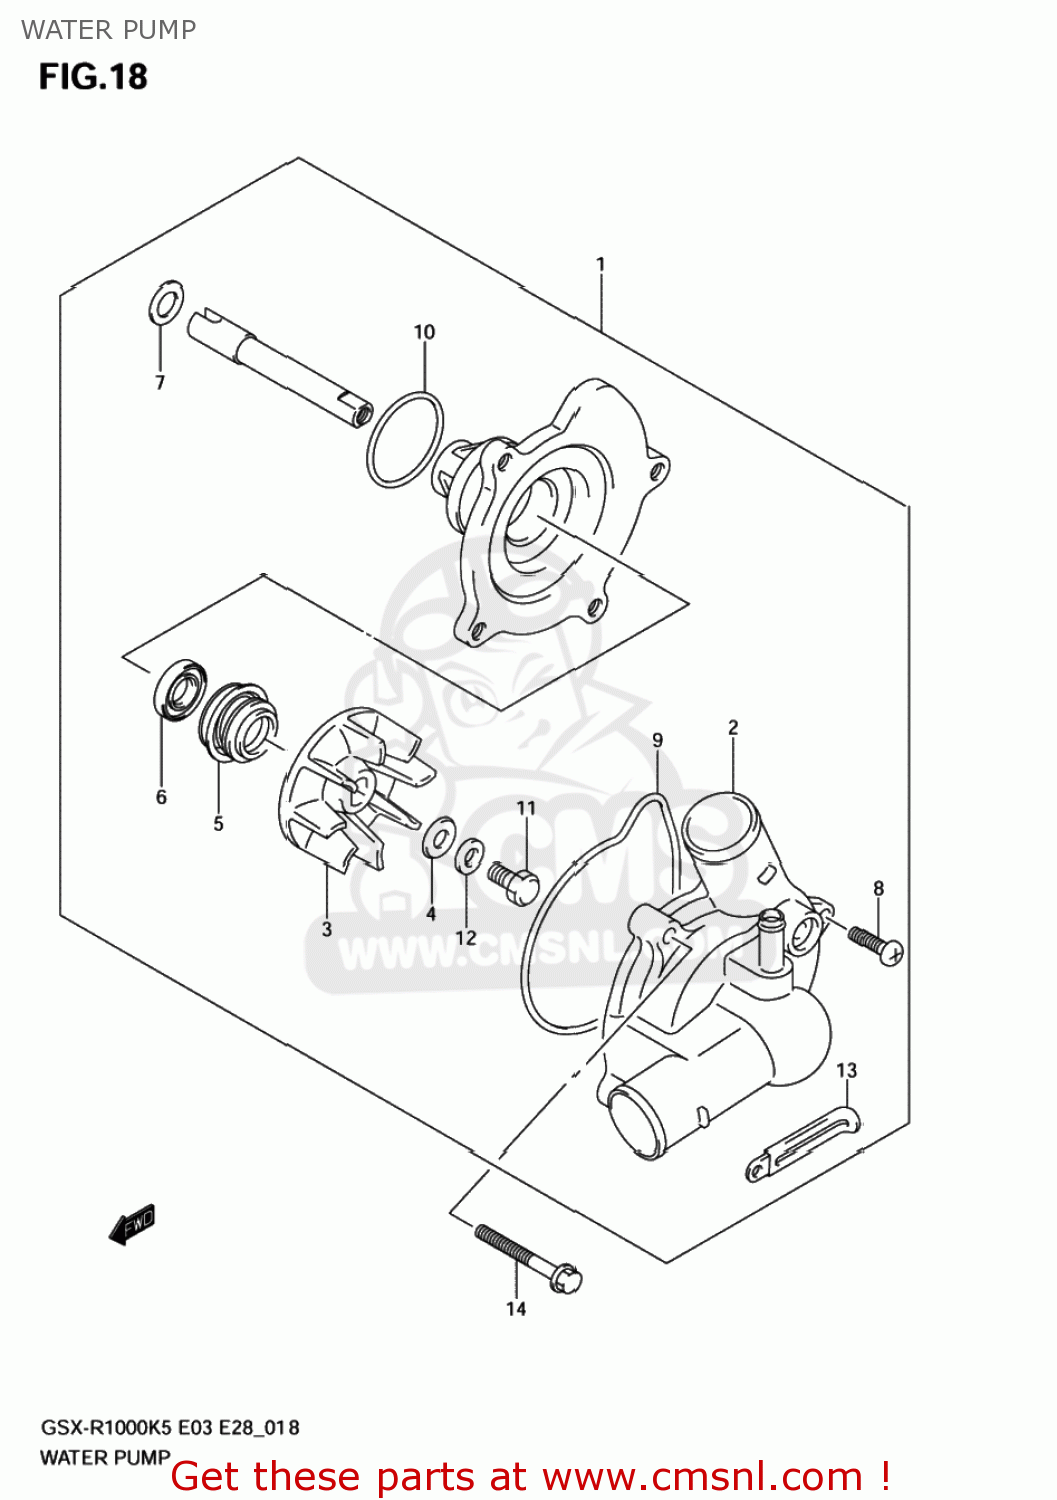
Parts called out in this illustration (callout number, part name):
1	PUMP ASSY,WATER
2	CASE WATERPUMP
3	IMPELLER
4	GASKET(6X15X2.2) (NAS)
5	SEAL,MECHANICAL
6	SEAL,OIL(10X21X5)
7	WASHER
8	SCREW 6X16
9	O RING
10	O RING,WATER PUMP HOLDER
11	BOLT(6X13)
12	WASHER
13	CLAMP(L:45)
14	BOLT
